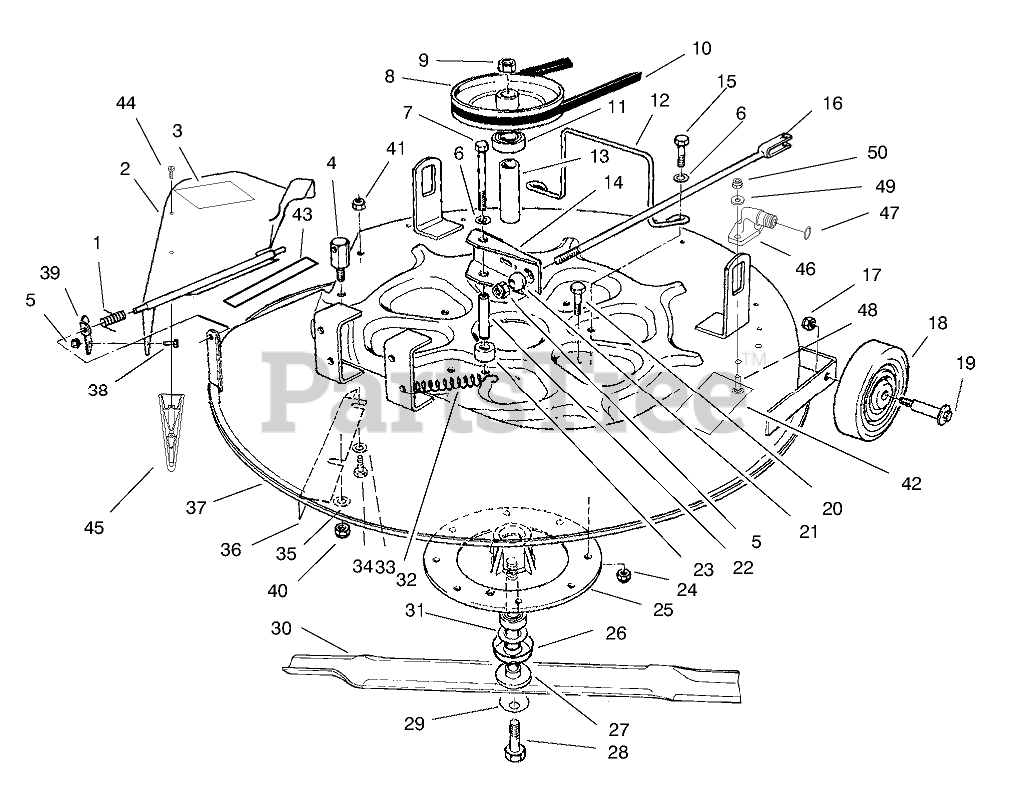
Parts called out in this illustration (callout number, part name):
1	SPRING
2	Deflector (Incl. Ref. #3)
3	DECAL-DANGER
4	POST-PIVOT
5	NUT-HEX
6	WASHER-PLAIN
7	SCREW-HH
8	PULLEY-DECK
9	NUT-HEX
10	V-BELT
11	BEARING-BALL
12	GUIDE-DECK BELT
13	SPACER-BEARING
14	DECK BRAKE ASSEMBLY
15	SCREW-HH
16	DECK BRAKE ROD WA
17	NUT-LOCK, NI
18	WHEEL-DECK
19	BOLT-WHEEL
20	SCREW-HH
21	BALL-SWIVEL, STOP
22	POST-BRAKE MTG
23	SPACER-DECK BRAKE
24	NUT-LOCK, NI
25	CASTING-SPINDLE
26	SHIELD-BEARING
27	SHAFT-SPINDLE
28	SCREW-HH
29	WASHER-BELLEVILLE
30	Blade
31	SPACER
32	SPRING-EXTENSION
33	WASHER-FLAT
34	SCREW-HHF
35	WASHER-FLAT
36	BAFFLE PLATE RED
37	Deck (Incl. Ref. #42 & 43)
38	SCREW-HH
39	BRACKET-DEFLECTOR
40	NUT-LOCK, NI
41	NUT-LOCK, NI
42	DECAL-DANGER
43	DECAL-DANGER
44	SCREW-PPH
45	KICKER
46	FITTING-WASHOUT
47	O-RING
48	BOLT-CARR
49	WASHER-FLAT
50	NUT-LOCK, NI
